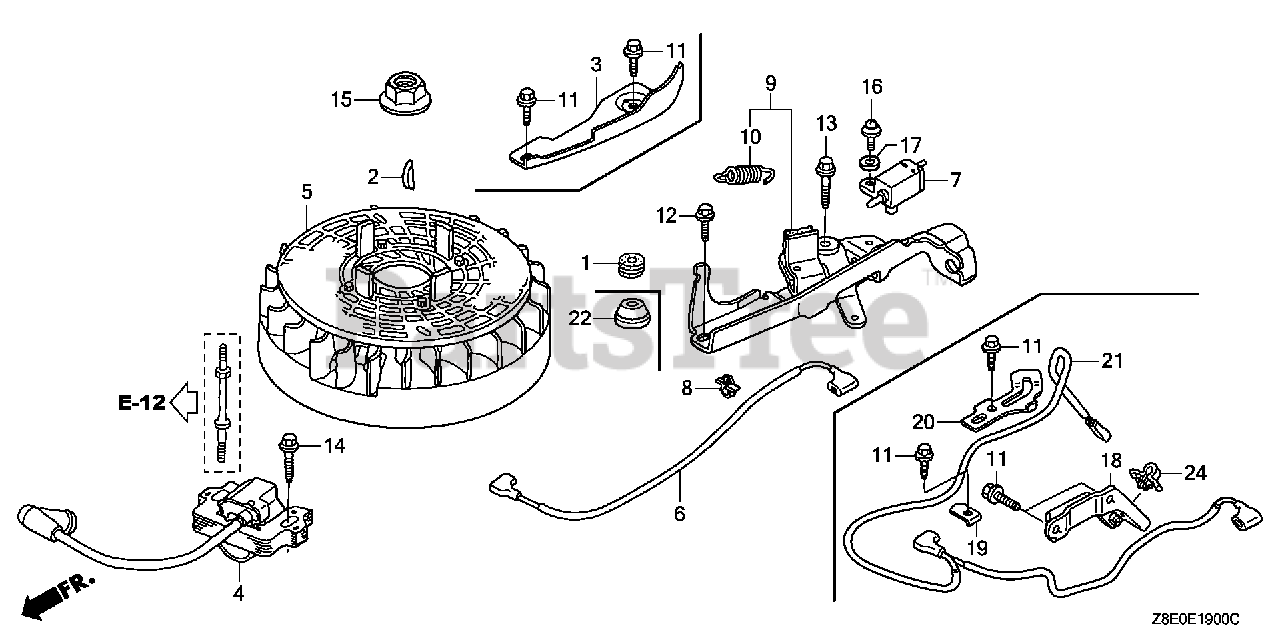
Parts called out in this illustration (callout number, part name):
2	KEY, SPECIAL WOODRUFF (25X18)
3	PLATE, SIDE
4	COIL ASSY., IGNITION (USE FOR F/W OF TEC) (TEC) Use up to Engine SN 3747197.
4	COIL ASSY., IGNITION (PHELON)
4	COIL ASSY., IGN
5	FLYWHEEL ASSY. (PHELON) (USE FOR IGN. COIL OF PHELON)
5	FLYWHEEL ASSY. (TEC) (USE FOR IGN. COIL OF TEC)
11	BOLT, FLANGE (6X12) (CT200)
14	BOLT, FLANGE (6X23)
14	BOLT, FLANGE (6X20) (CT200)
15	NUT, FLANGE (14MM)
